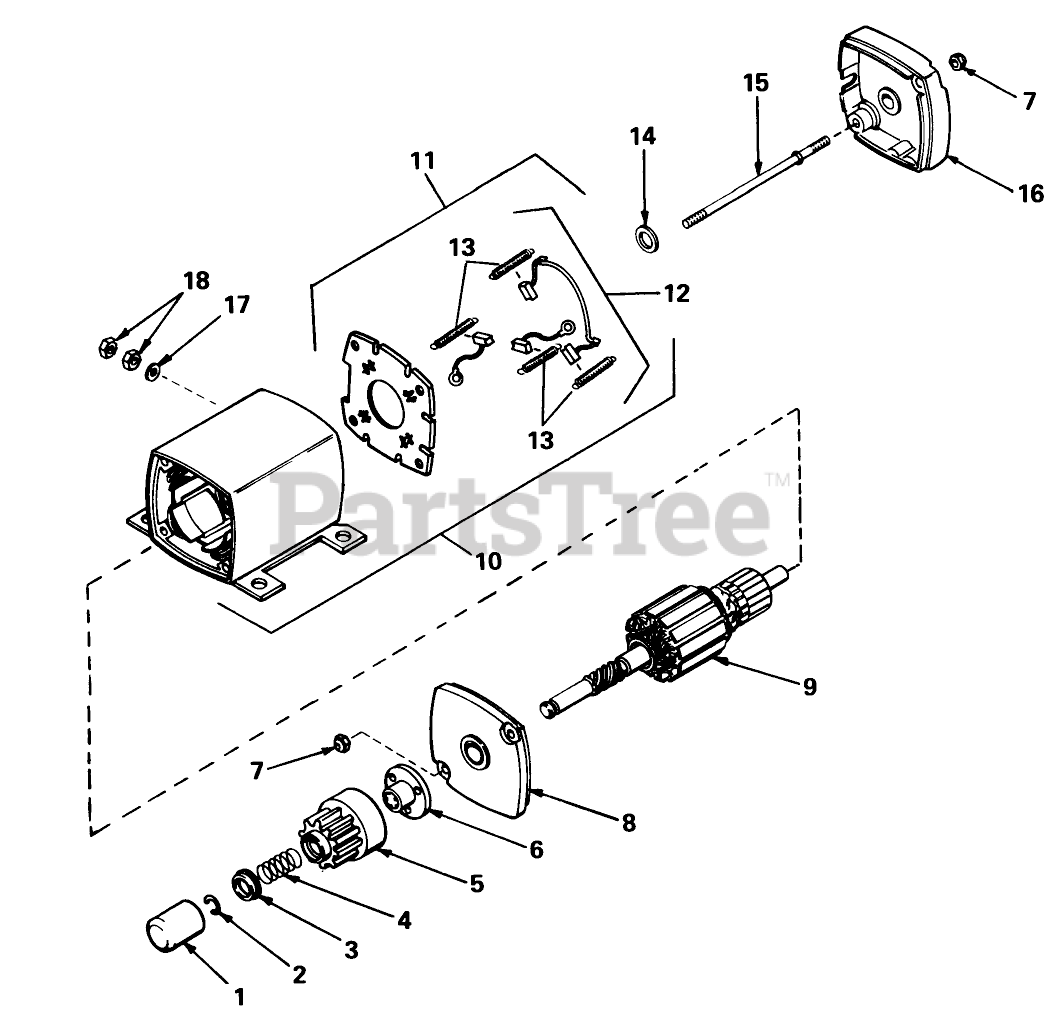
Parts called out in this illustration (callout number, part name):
1	Cover-Dust
2	Ring, Retainer
3	Retainer-Spring
4	Spring-Anti Drift
5	Gear
6	Nut-Engaging
7	Nut-Lock
8	Cap Assy., Drive End
9	Armature
10	Housing Assembly (Incl. Ref. #11)
11	Card Assy., Brush (Incl. No. 12)
12	Brush Spring Kit (Incl. 4 pcs. of #13)
13	1545D SUP TO W/3256
14	Washer-Thrust
15	Bolt
16	2035A67 WIZARD W/34
17	Washer
18	61710/VAR.HILLER AT
